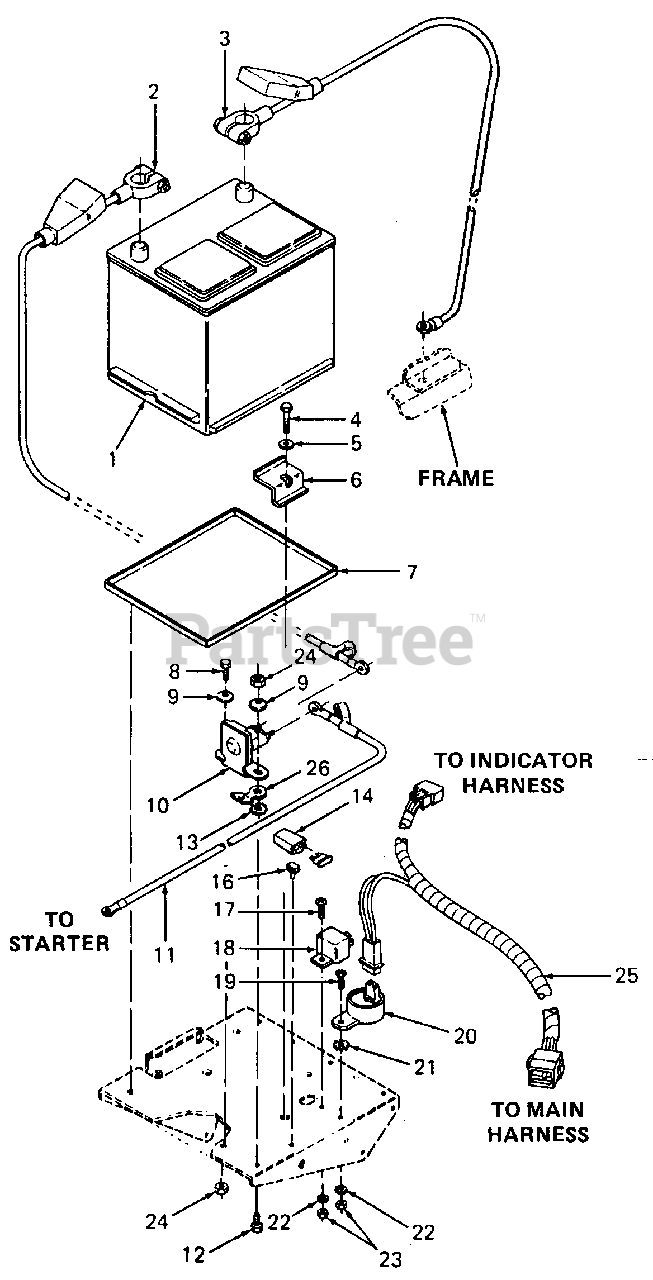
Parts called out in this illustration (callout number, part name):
1	Battery
2	Cable, Positive Battery
3	Cable, Negative Battery
4	Screw, Hex Cap, 5/16-18 X 1.38 Lg
5	Washer, Flat, .34 X .68 X .062 Thk
8	Screw, Hex Cap, 1/4-20 X .62 Lg GR5
9	Washer, Bell, .265 X .75 X .062 Thk
10	Solenoid
11	Cable, Starter
12	Screw, Hex Cap, 1/4-20 X 1.0 Lg
13	Washer, Int-Ext, 1/4
14	Holder, Fuse
16	Clip, Fuse Holder Mtg
17	Screw, Truss Mach, #10-24 X .50 Lg
18	Relay
19	Screw, Truss Mach, #10-24 X .50 Lg
20	Indicator, Voltage
21	Washer, External, #10
22	Washer, Lock, #10
23	Nut, Hex, #10-24
24	Nut, Hex Center Lock, 1/4-20
25	Battery Harness
26	Lug, Quick Connect
